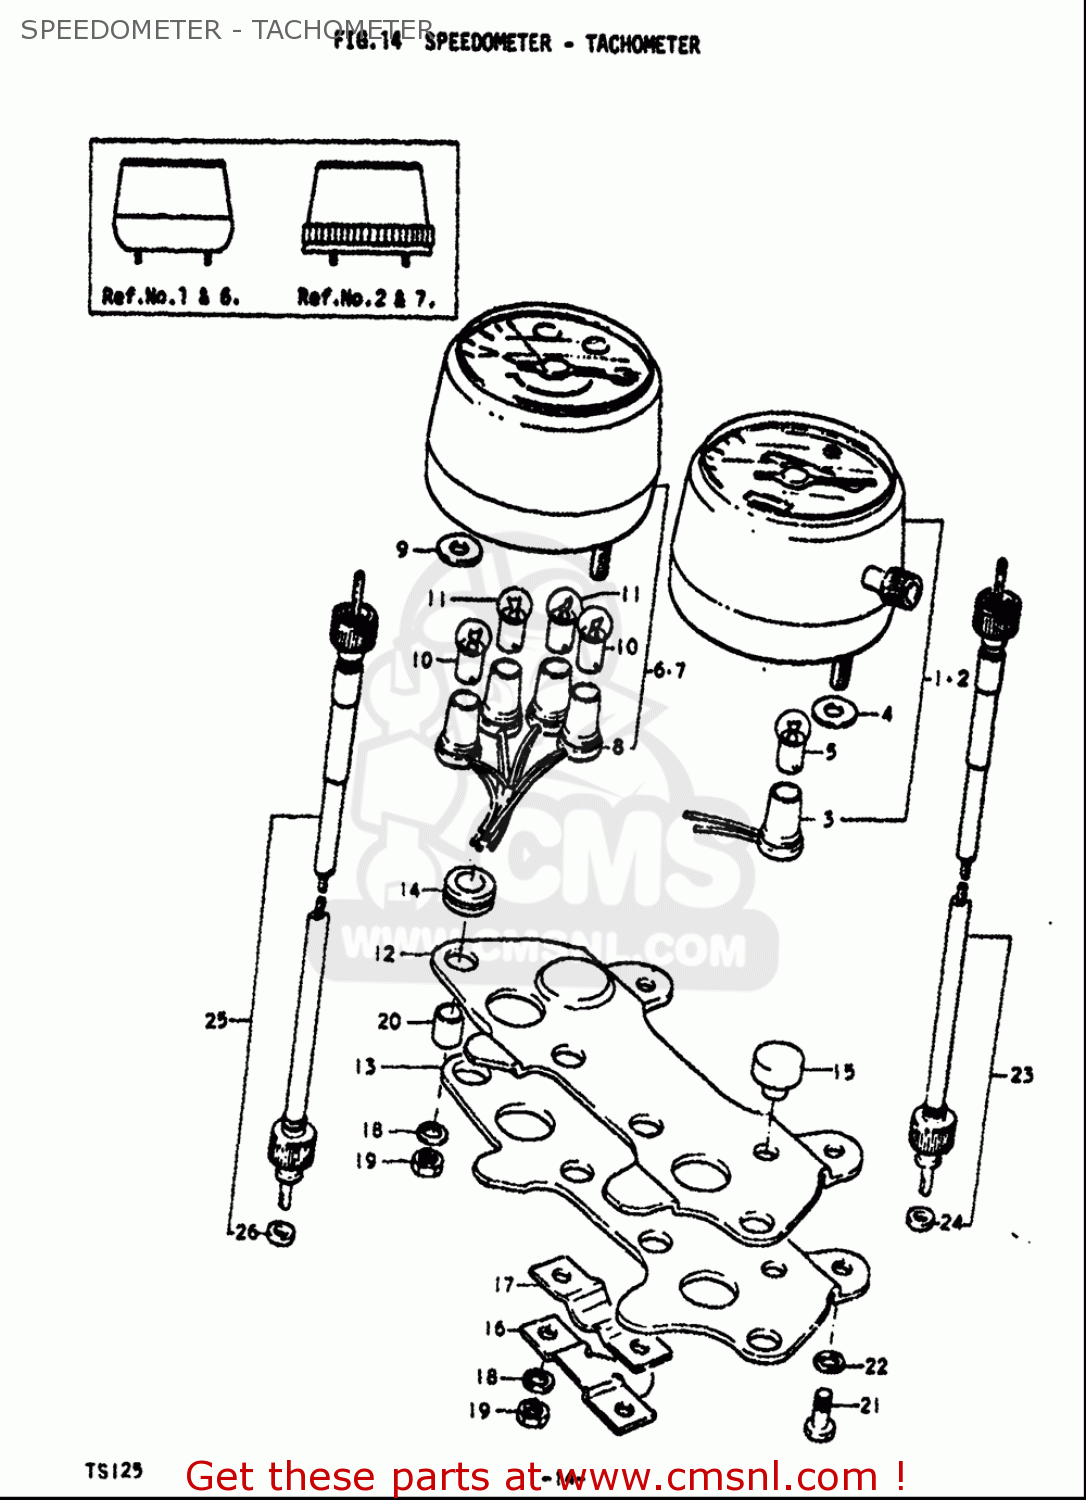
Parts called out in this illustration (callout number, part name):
4	WASHER(5.5X16X1.2)
5	BULB(6V/3W)
9	WASHER(5.5X16X1.2)
10	BULB(6V/3W)
11	BULB(6V1.7W,STANLEY,A61A)
14	CUSHION
18	WASHER,LOCK
19	NUT
20	SPACER,METER NO.2
21	BOLT
22	WASHER,LOCK
23	CABLE ASSY,SPEEDOMETER
24	SEAL,OIL METER CABLE
26	SEAL,OIL SPEEDOMETER CABLE
